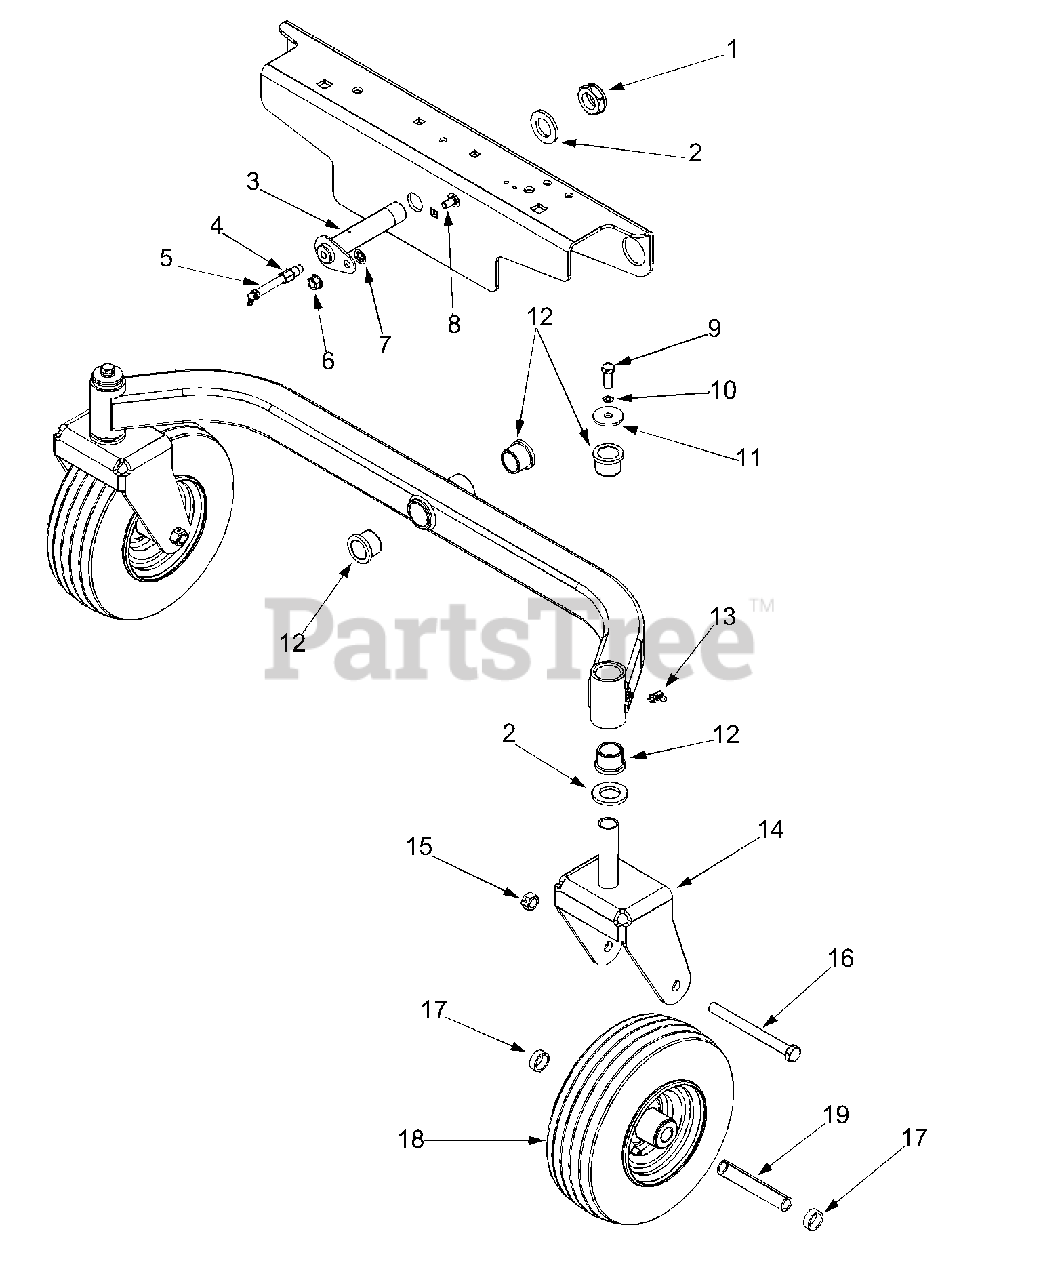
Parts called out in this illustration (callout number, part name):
1	Hex Lock Nut, 1.0-14
3	Pin Ass'y, Pivot
4	Adapter, 1/8 NPTF x 1/8 NPTF
5	Grease Fitting, 65° w/Extension
6	Hex Flange Lock Nut, 3/8-16
7	Push Nut, 3/8 ID
8	Carriage Bolt, 3/8-16 x .75
9	Hex Cap Screw, 3/8-16 x 1.0
10	Lock Washer 3/8
11	Flat Washer 3/8 x 1.5
12	Flange Bearing 1.0 ID
13	Grease Fitting
15	Hex Center Lock Nut 1/2-20
16	Hex Cap Screw, 1/2-20 x 5.5
17	Spacer, .79 ID x .347 Lg
18	Wheel Comp 11.0 x 4.0 x 5.0
